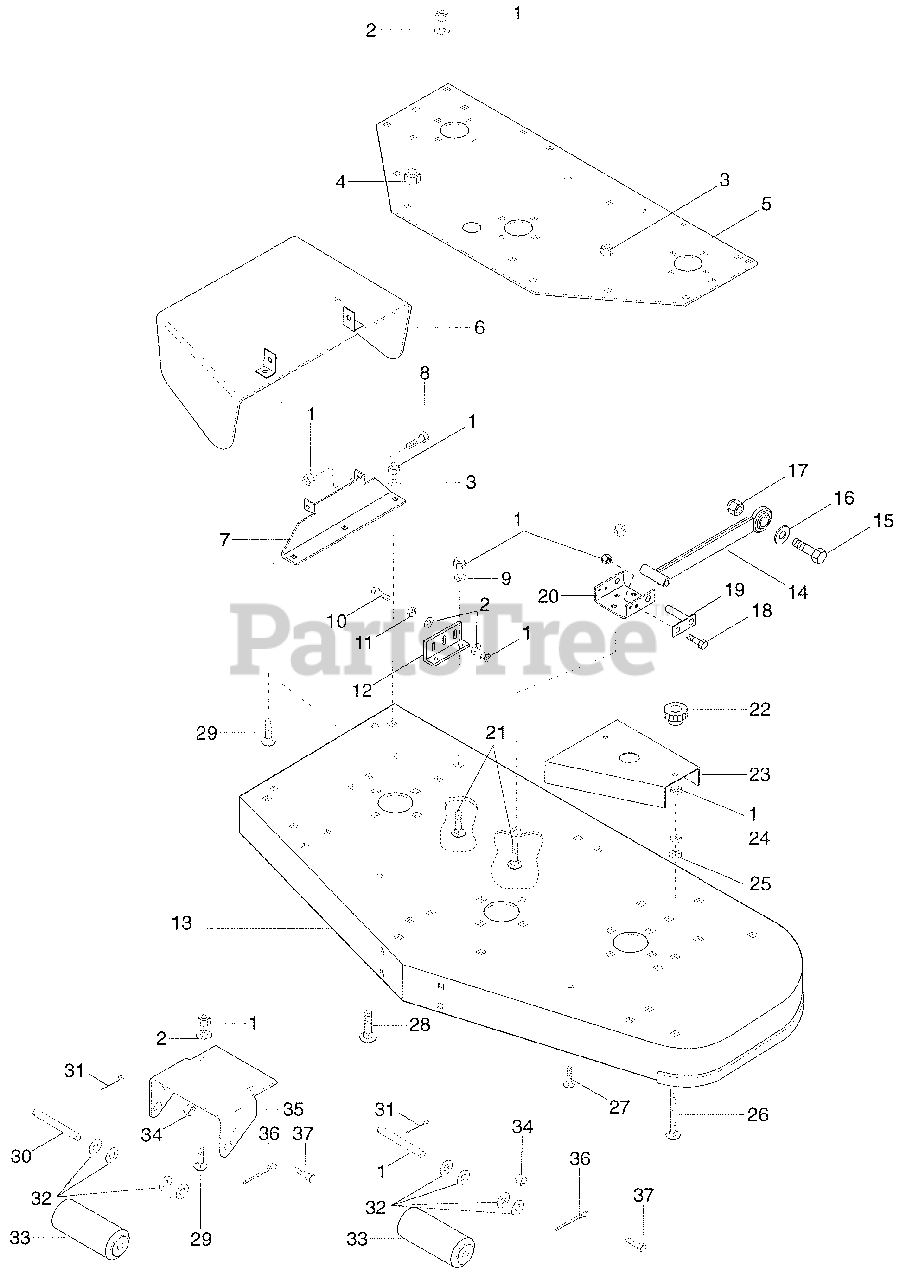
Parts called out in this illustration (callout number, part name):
1	Nut Locking Nylon .375-16 Grade 2
2	Washer Flat Steel .406 X .812 X .065
3	Nut Locking Nylon .312-18 Grade 2
4	Nut Locking Nylon .50-13 Grade 2
5	Plate, 60" Support
6	Weldment, Discharge Chute
7	Bracket, Discharge
8	Bolt Hex .38-16 X 1.00 Grade 5
9	Bushing .406 X .750 X .188
10	Bolt Hex .38-16 X 1.50 Grade 5
11	Nut Hex .375-16 Grade 2
12	Bracket, Mower Mounting (60" Mower)
13	Weldment, Deck 60" Mower PM200
14	Weldment, Mower Mounting Arm
15	Bolt Hex .87-9 X 2.75 Grade 5
16	Washer Flat Steel .094 X .250 X .020
17	Nut Loxking .875-9
18	Bolt Hex .38-16 X .75 Grade 5I
19	Weldment, Mower Mounting Pin
20	Bracket, Mower Mounting (Rear)
21	Bolt Round Head Square Neck .38-16 X 1.25
22	Knob
23	Guard Pulley LH 60" Mower
24	Nut Hex .312-18 Grade 2
25	Washer Lock .313 X .078
26	Bolt Round Head Square Neck .31-18 X 3.50
27	Bolt Round Head Square Neck .31-18 X .62
28	Bolt Round Head Square Neck .50-13 X 1.00
29	Bolt Round Head Square Neck .38-16 X 1.0
30	Shift, Center Roller
31	Pin Cotter .25 X 1.00
32	Washer Flat Steel .656 X 1.312 X .095
33	Roller, Gage
34	Nut Locking Nylon .250-20 Grade 2
35	Bracket Roller RH
36	Pin Cotter .250 X 2.00
37	Bolt Hex .25-20 X .75 Grade 5
